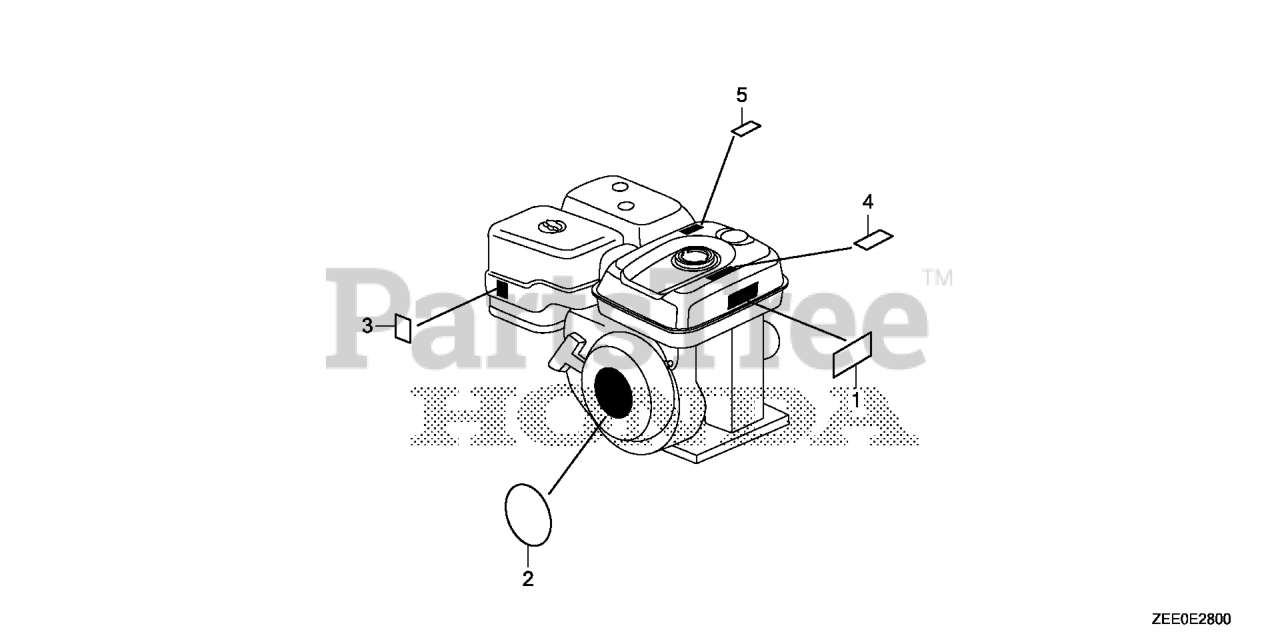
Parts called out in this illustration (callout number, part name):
1	MARK, OPERATOR CAUTION (PICTOGRAPH)
2	EMBLEM (GX200)
3	MARK, CHOKE
4	MARK, THROTTLE INDICATION
